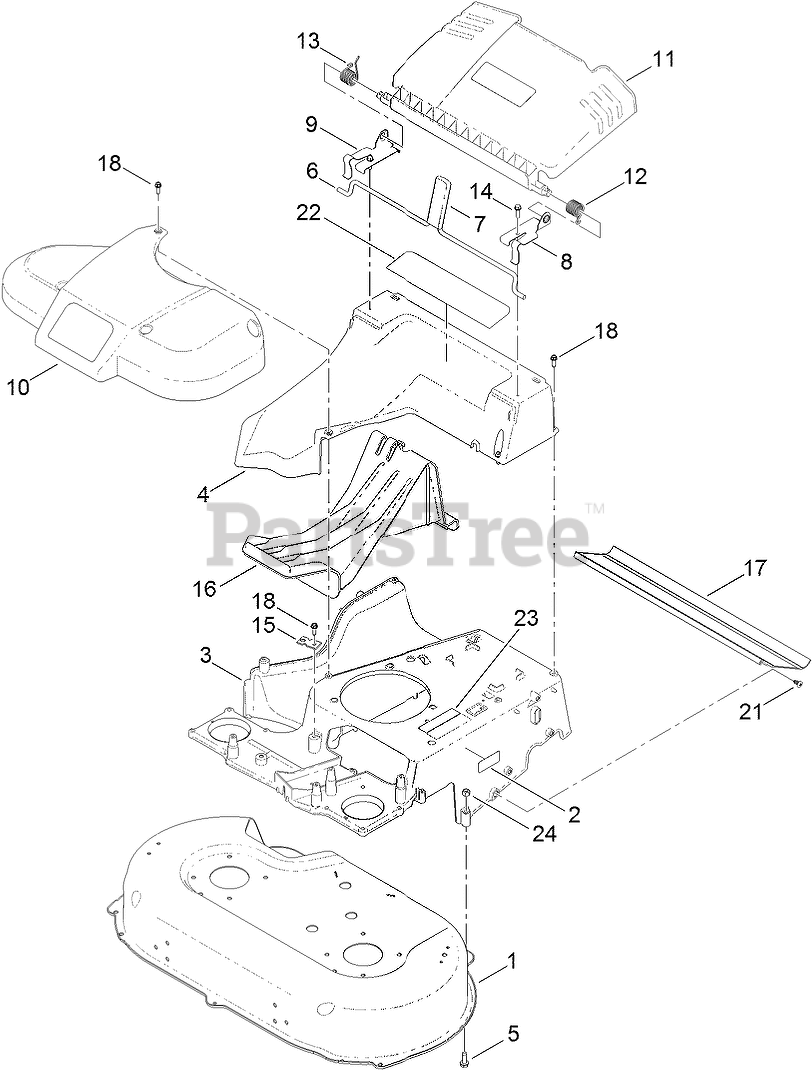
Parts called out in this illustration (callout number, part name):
1	HOUSING ASM
2	DECAL-LOCATION, SERVICE DEALER
4	CHUTE
5	SCREW-CARR
6	ROD-RELEASE, HANDLE
7	GRIP-LEVER
8	BRACKET-DOOR, LH
9	BRACKET-DOOR, RH
10	BELT COVER ASM
11	REAR DEFLECTOR ASM
12	SPRING-TORSION
13	SPRING-TORSION
14	SCREW-HWH
15	BRACKET-CABLE, TRACTION
16	PLUG-MULCH
17	SHIELD-TRAILING
18	SCREW-HWHTF
21	SCREW-PTH
22	DECAL-POSITION, HANDLE
23	DECAL-ARRESTER, SPARK
24	NUT-LOCK, NI
